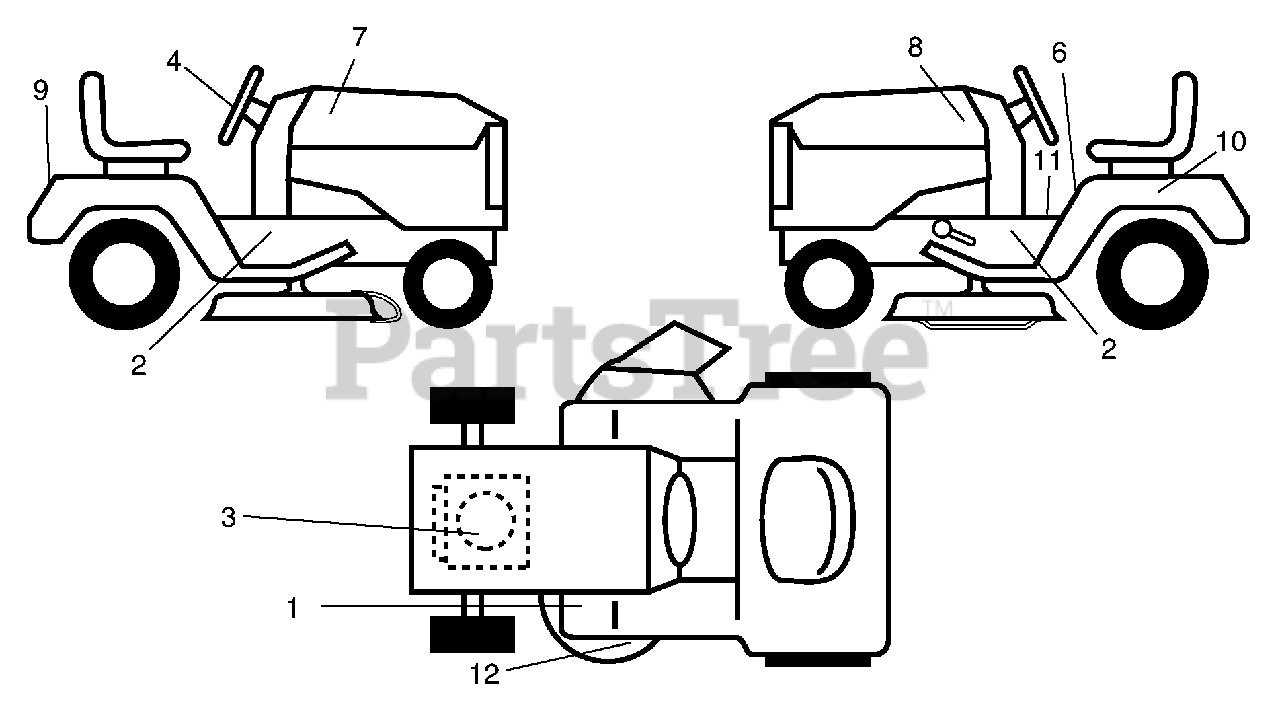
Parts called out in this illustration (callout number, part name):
1	Decal, Clutch/Brake
2	Decal, Chassis
3	Decal, Engine HP
4	Decal, Steering
6	Decal, Fender Danger English
7	Decal, Hood RH
8	Decal, Hood LH
9	Decal, Fender
10	Decal, Caution, Battery
11	Decal, Oper Sdl P/L Gear Dr
12	Decal, V-Belt Sch.
